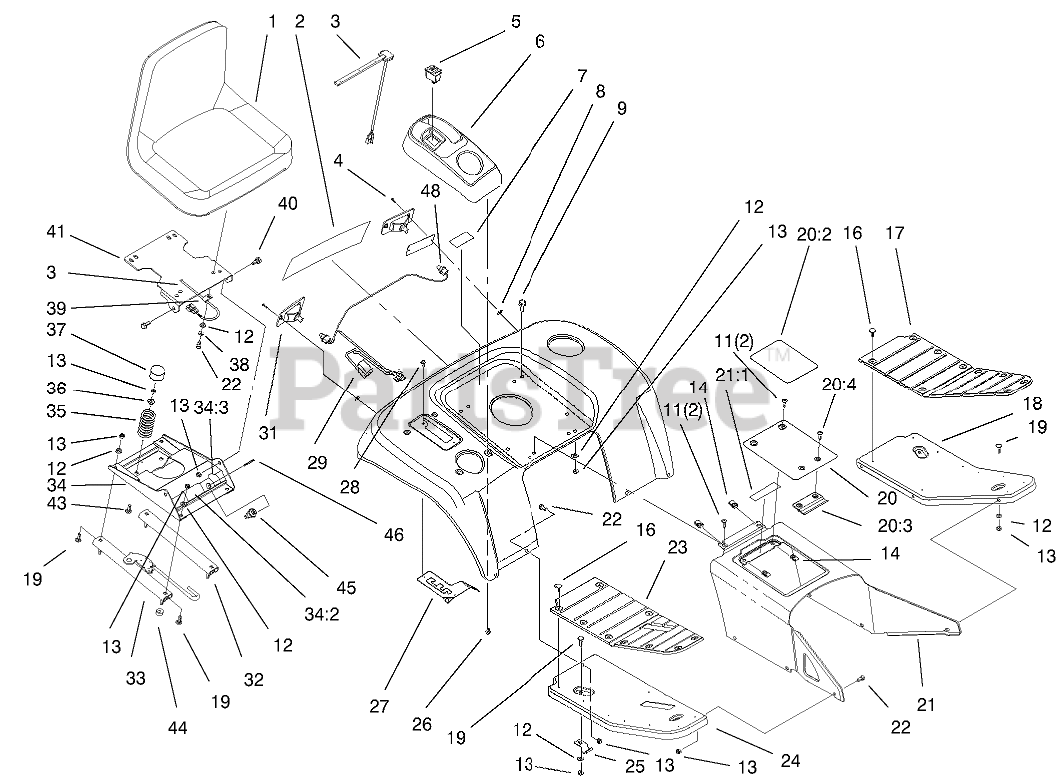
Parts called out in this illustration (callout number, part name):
1	SEAT
2	DECAL - FENDER
3	SWITCH-SEAT
4	SCREW-PPH
5	SWITCH-CRUISE
6	Pod-Control Int-l (only on: 73580)
6	Pod-Control (only on: 73547)
7	Decal-USA (only on: 73547)
8	NUT-SPEED
9	SCREW-HHF
11	SCREW-HH
12	WASHER-PLAIN
13	NUT-LOCK, NI
16	FASTENER-PANEL
17	PAD-FOOTREST, LH
18	FOOTREST-LH
19	SCREW-CARR
20	ASM Cover/Decal (only on: 73547)
20	ASM-Tunnel Cover Europe (only on: 73580)
20:2	Decal-Danger (only on: 73547)
20:2	Decal-Danger Europe (only on: 73580)
20:3	RETAINER-COVER
20:4	Screw-PPH (only on: 73580)
21	ASM-Tunnel w/Decal (only on: 73547)
21	ASM-Tunnel w/Decal Europe (only on: 73580)
21:1	Decal-Danger (only on: 73547)
21:1	Decal-Warning (only on: 73580)
22	SCREW-HH
23	PAD-FOOTREST, RH
24	FOOTREST-RH
25	BRACKET-FOOTREST
26	SCREW-HHFTF
27	GATE-HI / LO SHIFT
28	SCREW-HWH
29	HARNESS-REAR
31	LAMP-TAILLIGHT
32	SLIDE-SLAVE, SEAT
33	SLIDE-LATCH, SEAT
34	Seat Base ASM (only on: 73547)
34	Seat Base ASM-Intl (only on: 73580)
34:2	Decal-Danger (only on: 73547)
34:3	Decal-Nmir Switch (only on: 73547)
35	SPRING-COMPRESSION
36	BUSHING
37	CAP-SPRING, SEAT
38	WASHER-LOCK
39	CLAMP-R
40	BOLT-SHOULDER
41	Mount-Seat
43	SCREW-CARR
44	WASHER-FLAT
45	STARTER SWITCH ASM
46	KEY-IGNITION
48	LIGHT BULB
